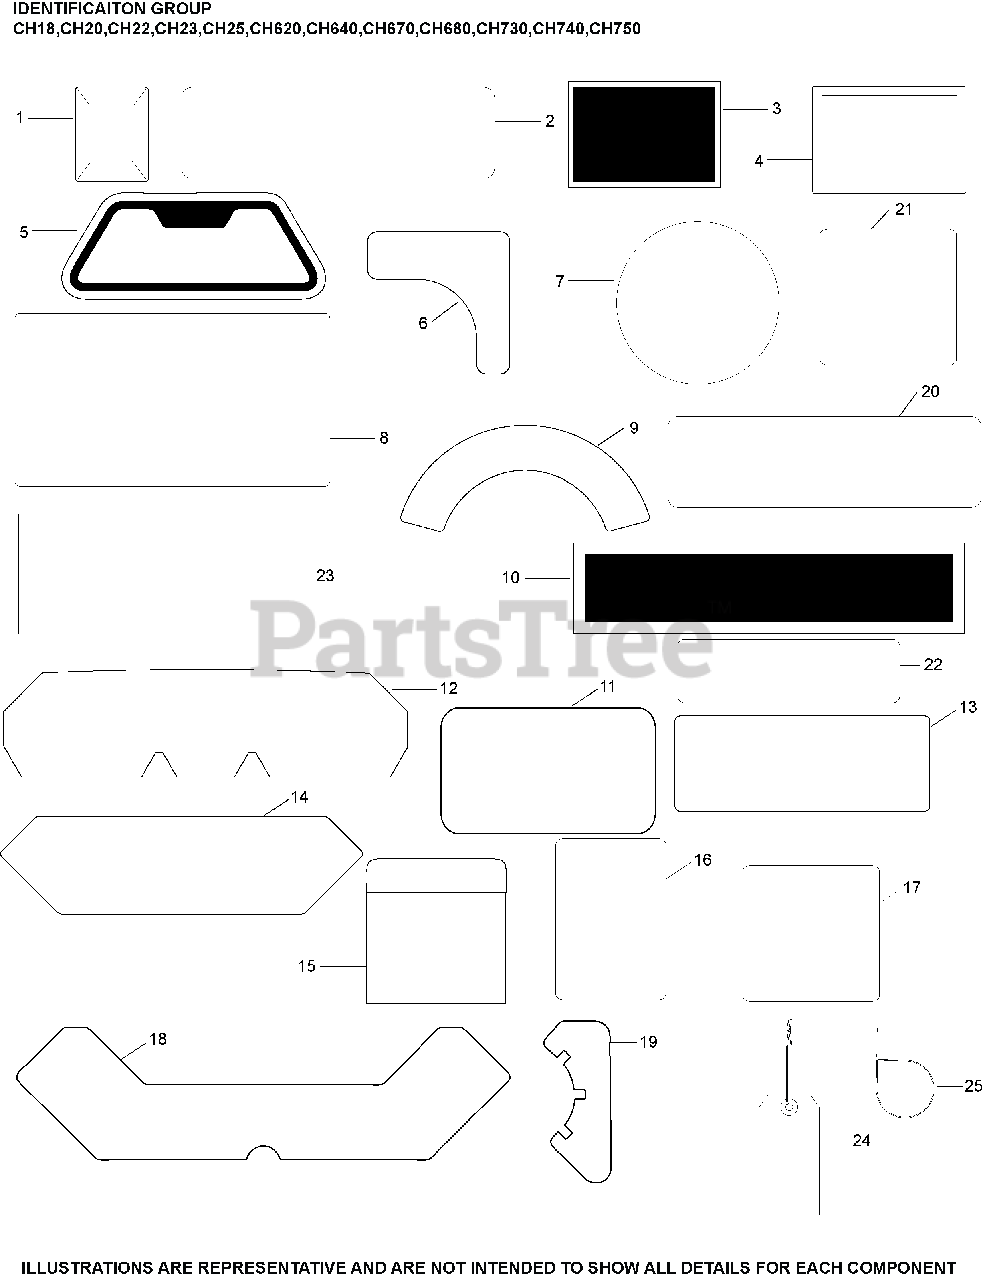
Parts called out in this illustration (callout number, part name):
1	LABEL, CLEAR LAMINATION
7	LABEL, GRASS SCREEN
20	DECAL LPAC, 23.5 HP/725cc/CH730
